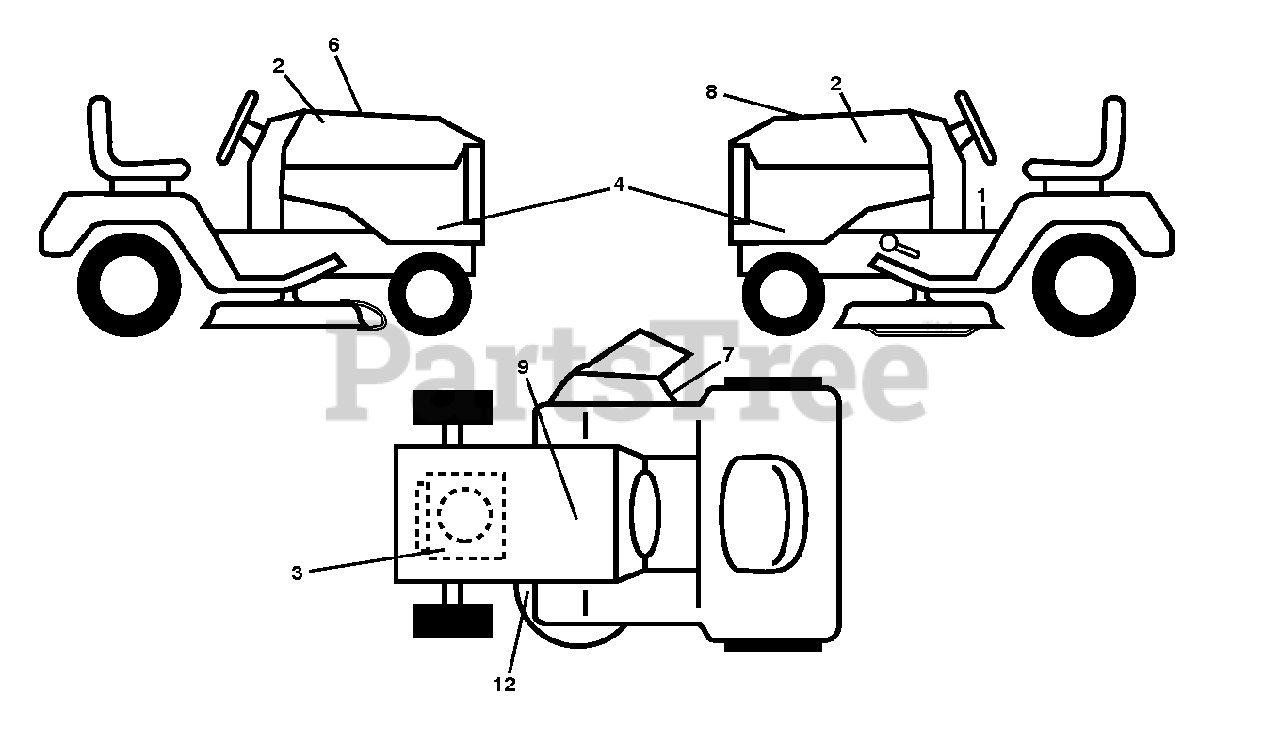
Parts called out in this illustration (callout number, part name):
1	DECAL.FENDER.WARNING
2	RP.DECAL.BADGE.170MM.TEXTLOGO
3	Decal, Engine BS22 OHP(2)INTEK GEN
4	DECAL.SDPNL.HGT2.YTH22V42.HUSQ
7	DECAL.WARN.KEEP.HAND.AWAY
8	DECAL.WARNING.CUST.RESP.E85.
9	DECAL BTRY SYMBOLS
12	DECAL V BELT SCHEMATIC
